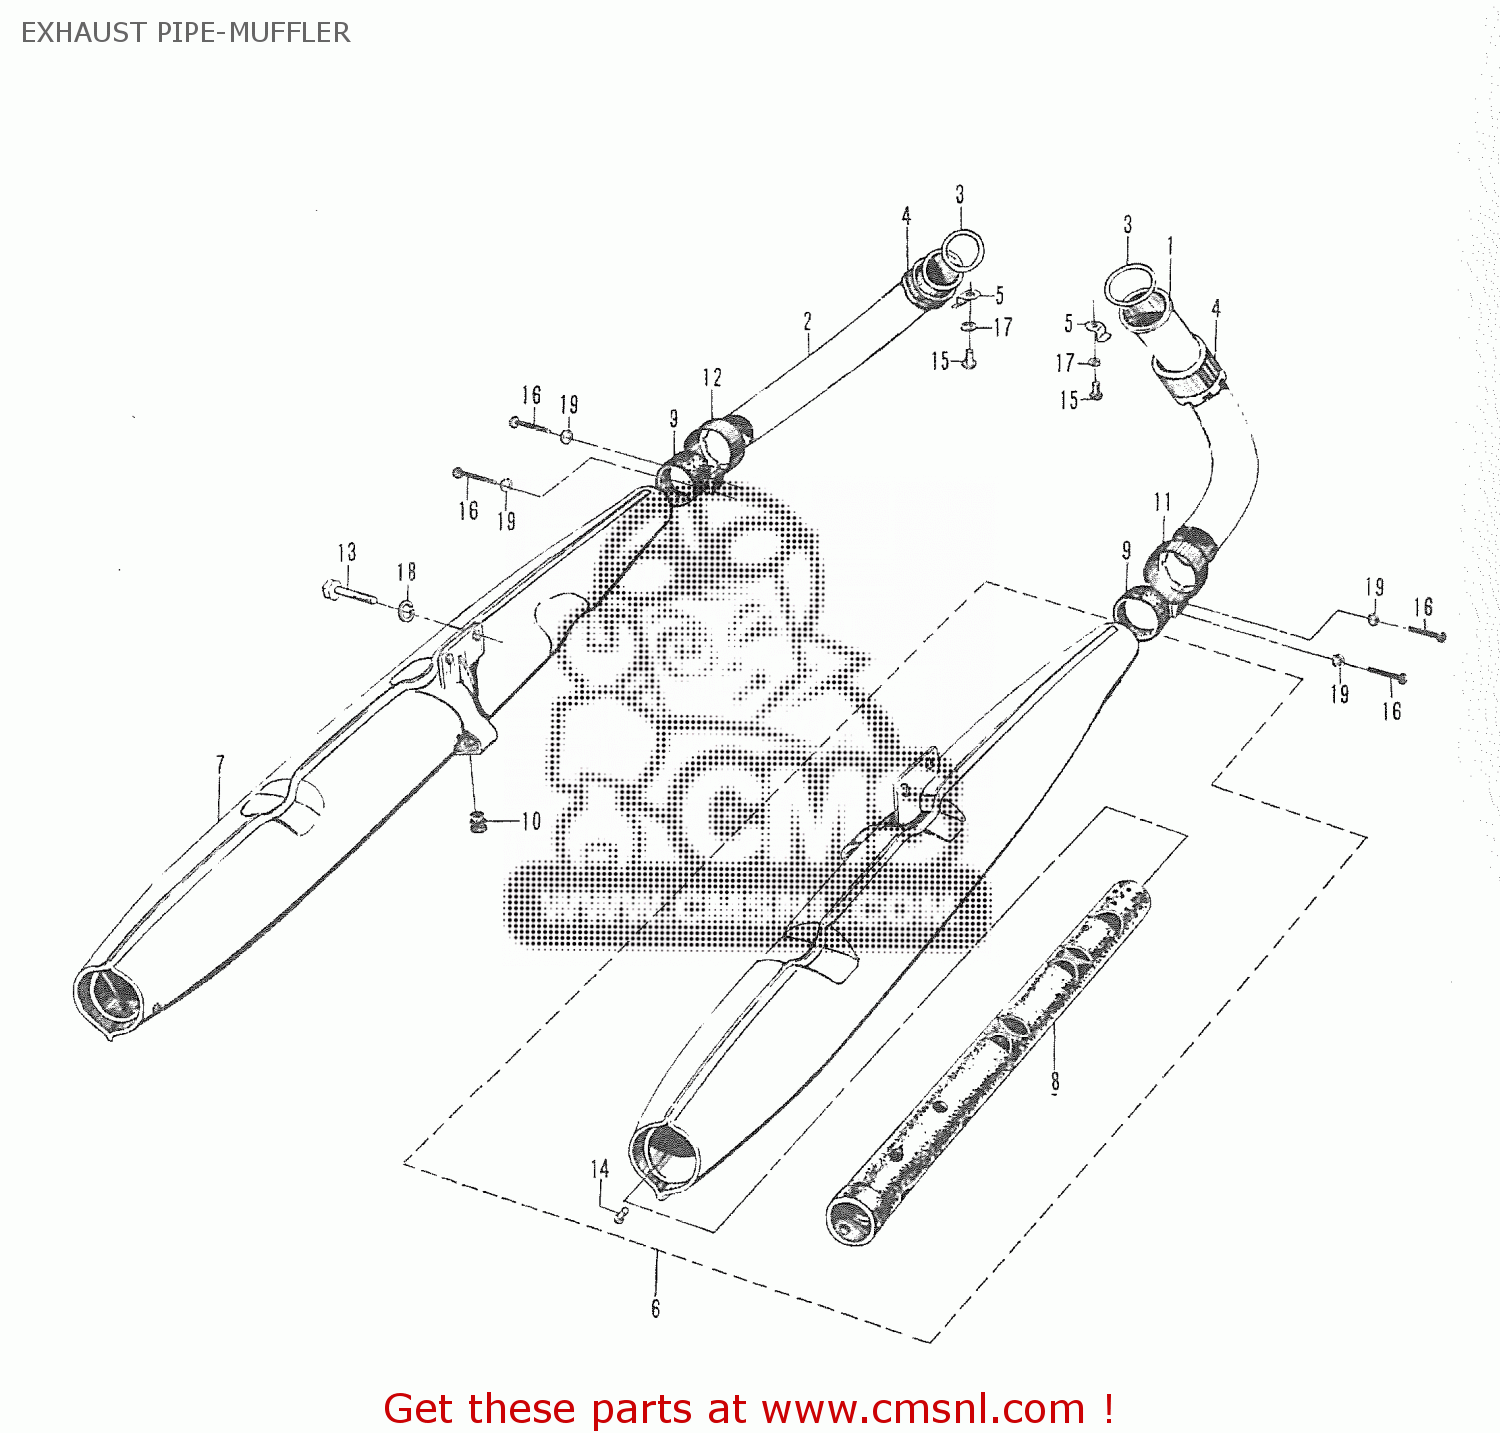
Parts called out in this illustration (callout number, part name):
1	RIGHT EXHAUST PIPE
2	LEFT EXHAUST PIPE
3	GASKET,EXHAUST PIPE (NAS)
4	CLAMP,EXHAUST PIPE
5	PLATE,EXHAUST PIPE
6	RIGHT MUFFLER ASS'Y
7	LEFT MUFFLER ASS'Y
8	MUFFLER BAFFLE PIPE
9	CONNECTOR,MUFFLER JOINT
10	CUSHION
11	RIGHT MUFFLER CONNECTOR BAND
12	LEFT MUFFLER CONNECTOR BAND
13	SMALL HEAD HEXAGON BOLT
14	CROSS HEAD SCREW
15	CROSS HEAD SCREW
16	CROSS HEAD SCREW
17	LOCK WASHER
18	LOCK WASHER
